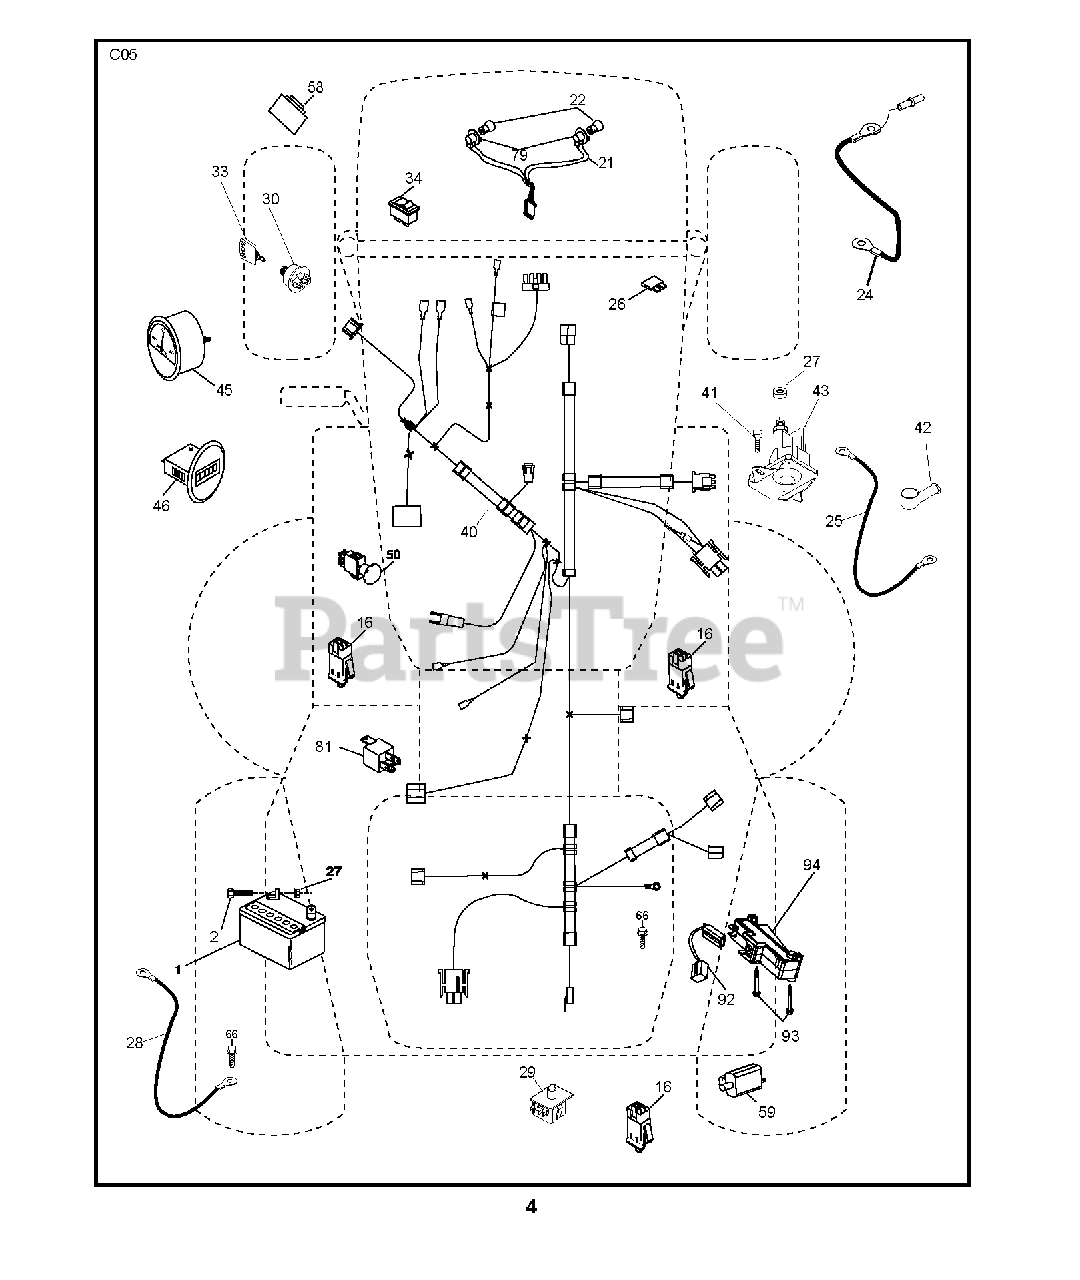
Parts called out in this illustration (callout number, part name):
1	BATTERY 12V .35 AMP
16	SWITCH INTERLOOK PUSH-IN
21	HARNESS.W/LIGHT SOCKET
22	LIGHTBULB
24	BATTERY CABLE GT
25	CABLE BATTERY
26	FUSE 20AMP
27	NUT
28	CABLE GROUND
29	SWITCH.SEAT.DP W/RAMPS
30	SWITCH.IGN.DELTA.W.LGH.ROS
33	KEY.CHAIN.BLISTER.PACK.GEN.INT
34	SWITCH LT
42	TERMINAL COVER
43	SOLENOID.W/BRASS.PLUNG
46	HOURMETER SNAP-IN
50	PTO SWITCH
58	BUZZER
79	BULB HOLDER ASM.
81	RELAY.ASSY.T
92	HARNESS.PIGTAIL.CONSLE
93	SCREW.PLASTITE
94	MODULE.REVERSE.ROS
